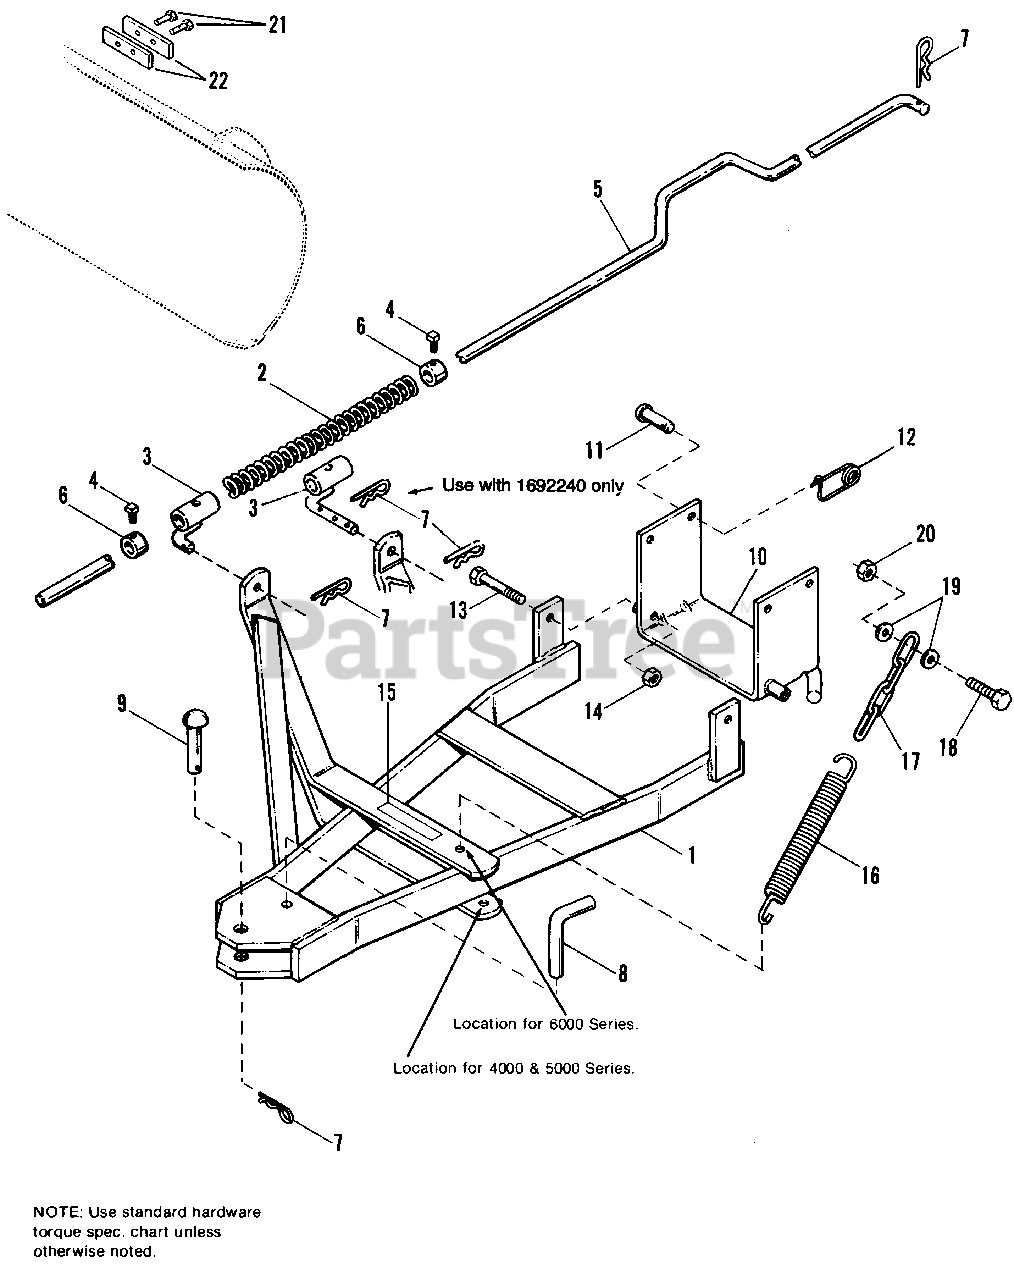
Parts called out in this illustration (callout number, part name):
1	BAR ASSY., Push
3	GUIDE ASSY., Rod (1691523 only)
3	GUIDE ASSY., Rod (1692240 only)
4	SETSCREW, 5/16-18 x 1/2
6	COLLAR, Set
7	SPRING, Clip (Qty. 3, 1691523 only)
10	BRACKET ASSY.
12	CLIP, Pin
13	CAPSCREW, 3/8-16 x 2-1/4
14	NUT, Lock, 3/8-16
15	I.D. PLATE
17	CHAIN, 4-Link
18	CAPSCREW, 5/16-18 x 1-1/4
19	WASHER, Plain, 5/16
20	NUT, Hex, Lock, 5/16-18
21	BAR STOP (1692240 only)
22	SCREW, Hex, Taptite, 5/16-18 x 1 (1692240 only)
